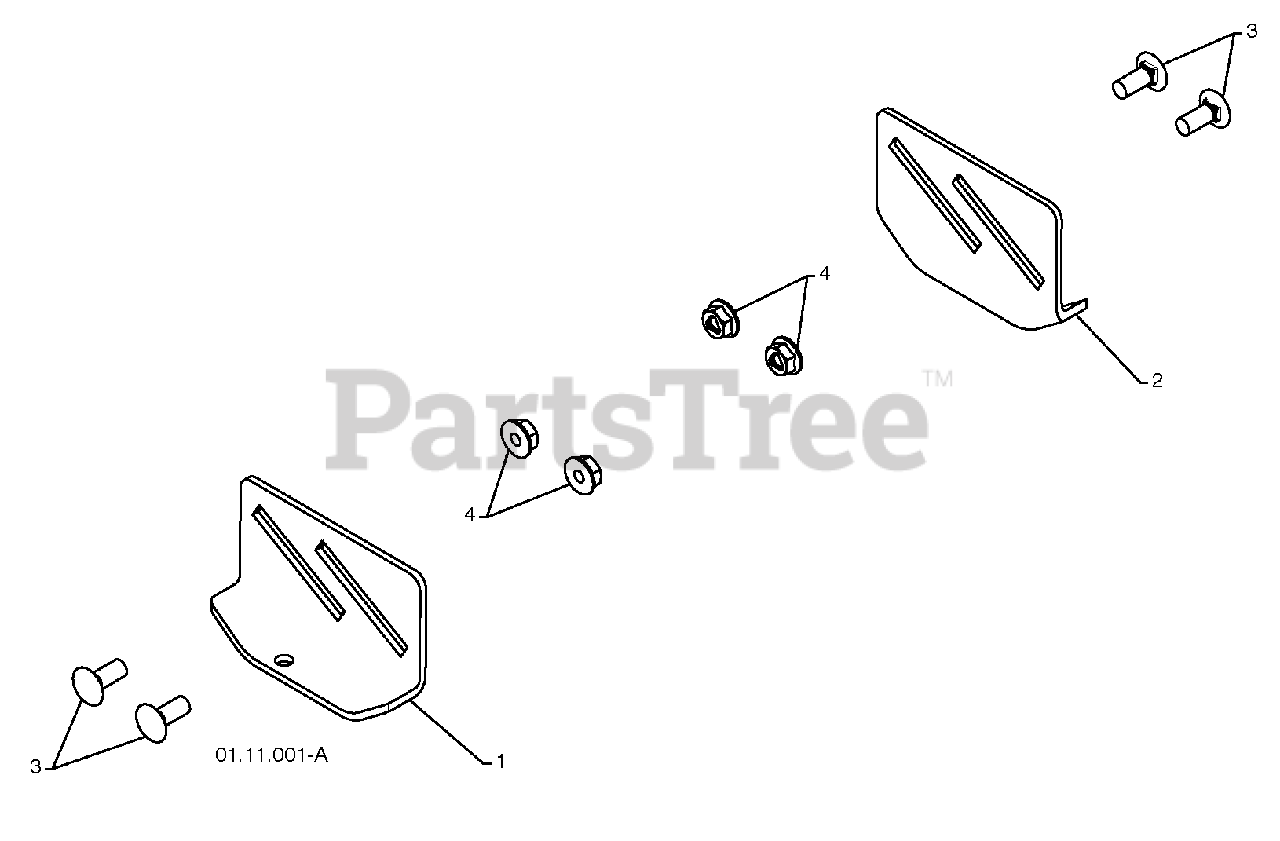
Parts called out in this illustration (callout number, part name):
1	SKID PLATE LH
2	SKID PLATE RH
3	CARRIAGE BOLT 5/16-18 X .75
4	NUT 5/16-18
